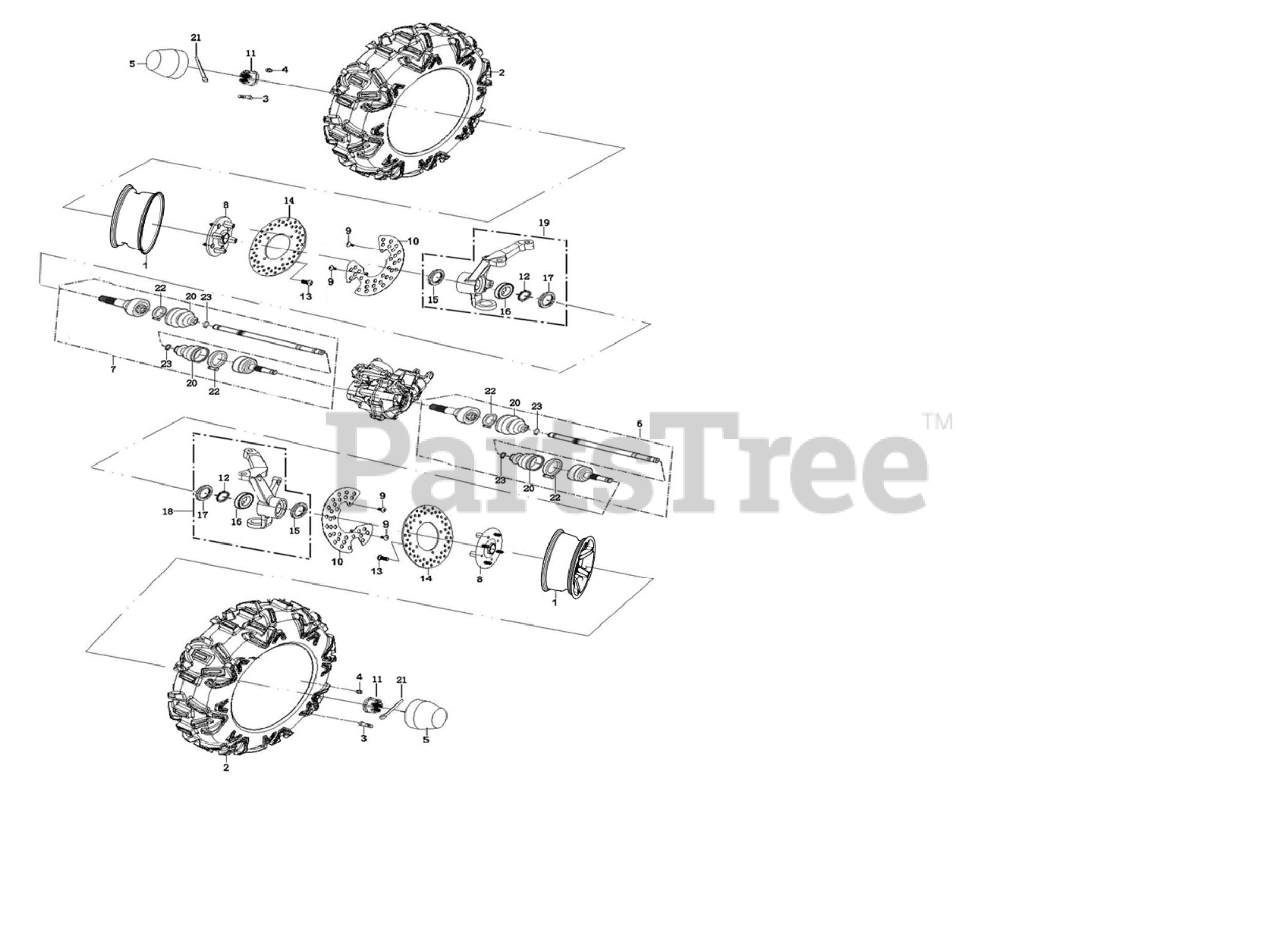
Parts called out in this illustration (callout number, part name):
1	RIM - FRONT
2	TIRE RADIAL - FRONT
3	valve core
4	Taper nut M10x1.25
5	DUST COVER HUB G
6	FRONT LEFT CONSTANT VELOCITY JOINT AA
7	FRONT RIGHT CONSTANT VELOCITY JOINT x
8	RIM - FRONT
9	Cross Recessed Plate Head Screw M6x12
10	FRONT DISC BRAKE SHIELD
11	SLOTTED NUT M24x1.5
12	Clip d0=60
13	SHOULDER BOLT CONE INSIDE HExAGONAL M8
14	DISC BRAKE - FRONT
15	Front Knuckle oil seal outward 38x 55x7
17	Front Knuckle oil seal inside 38x 60x7
18	STEERING KNUCKLE FRONT LEFT ASSEMBLY
19	STEERING KNUCKLE FRONT RIGHT ASSEMBLY
20	Axle Rubber boot F
21	COTTER PIN 3.2x50
22	CLAMP - LARGE BTB T
23	CLAMP - LARGE BTB U
